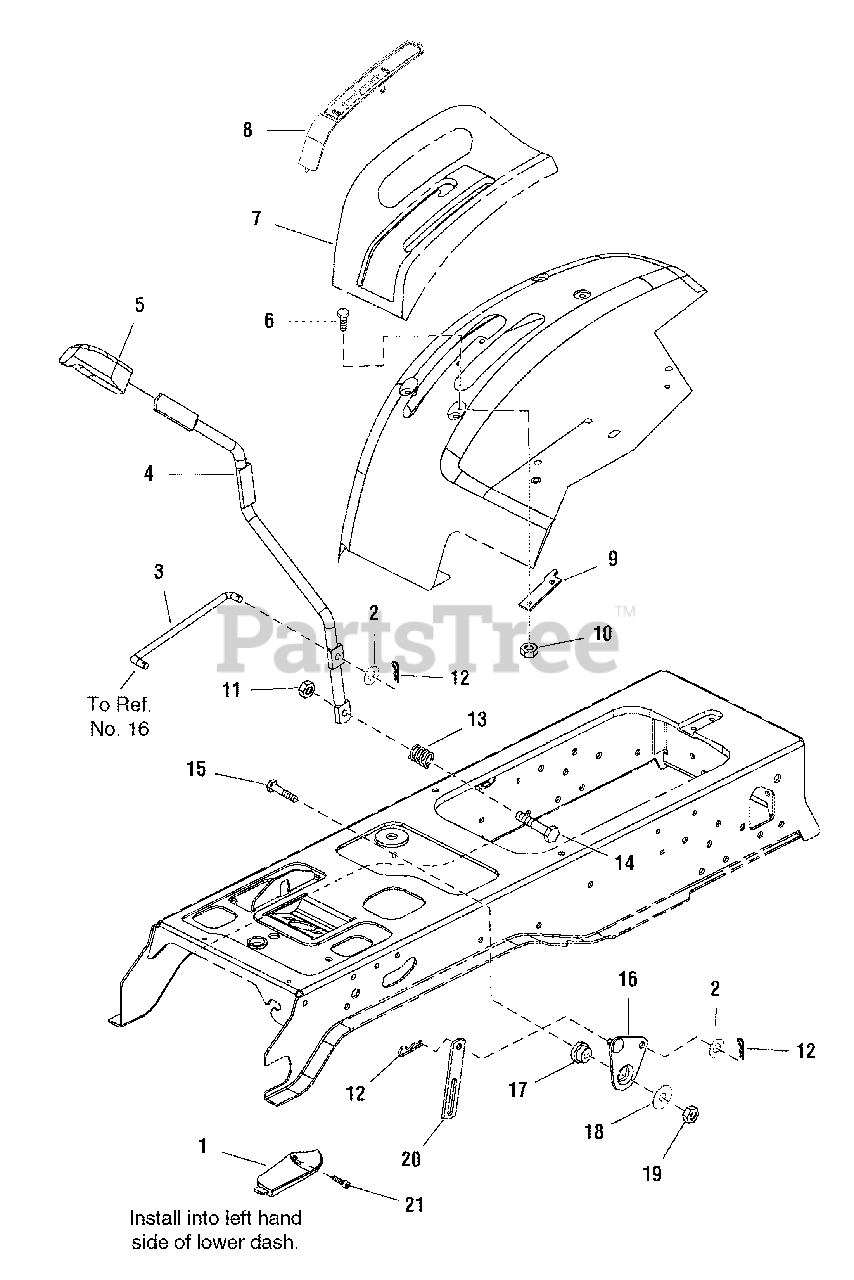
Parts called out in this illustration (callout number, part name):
1	COVER, Dash
2	WASHER
5	GRIP, Black Vinyl
6	CAPSCREW, Hex Head, 1/4-20 x 3/4
7	POD, RH
8	COVER, with Lift Icon, for Models without Cruise Control
10	NUT, Hex Lock ESNA, 1/4-20
11	NUT, Hex Flange Lock, 3/8-16
12	PIN, Quick
13	SPRING, Compression
14	CAPSCREW, Hex Head, 3/8-16 x 2
15	CAPSCREW, Hex Head, 5/16-18 x 1-1/4
16	CAM & PIN ASSEMBLY
17	SPACER
19	NUT, Hex Lock, 5/16-18
20	LINK
21	SCREW, Torx Head, # 8-16 x 1/2
